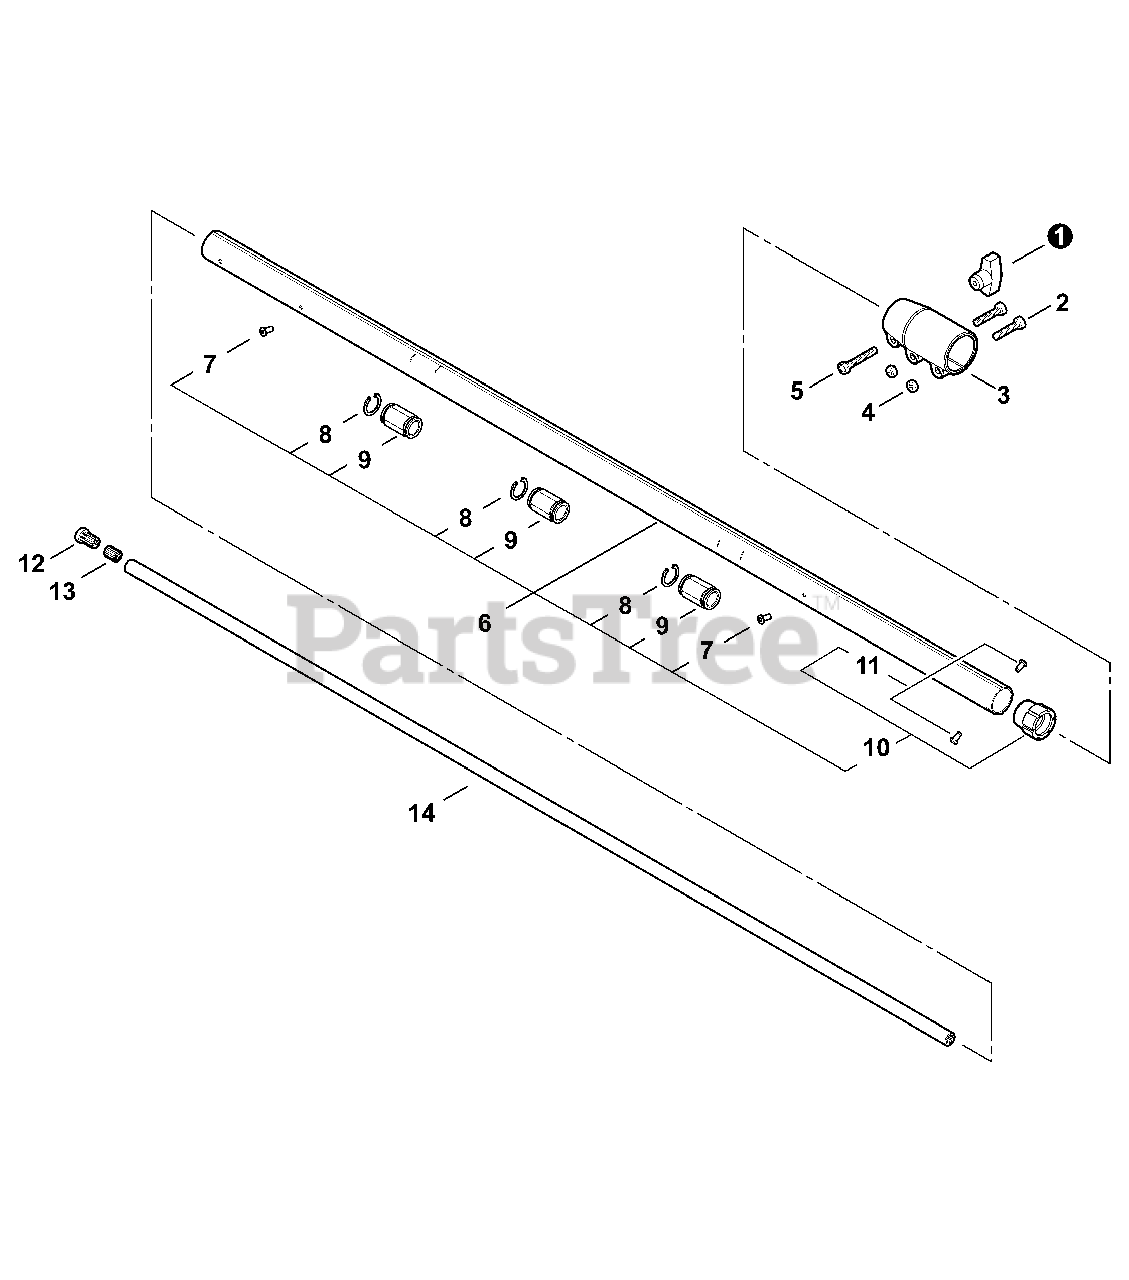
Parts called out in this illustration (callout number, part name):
1	THUMBSCREW
2	BOLT, TORX 5×20
3	COUPLING
5	BOLT 6×25
6	MAIN PIPE ASSY - BLACK
8	RING, RETAINING
9	GUIDE, SHAFT
10	HOLDER ASSY, BEARING
12	SOCKET - OUTER
13	SOCKET - INNER
14	DRIVESHAFT - UPPER
